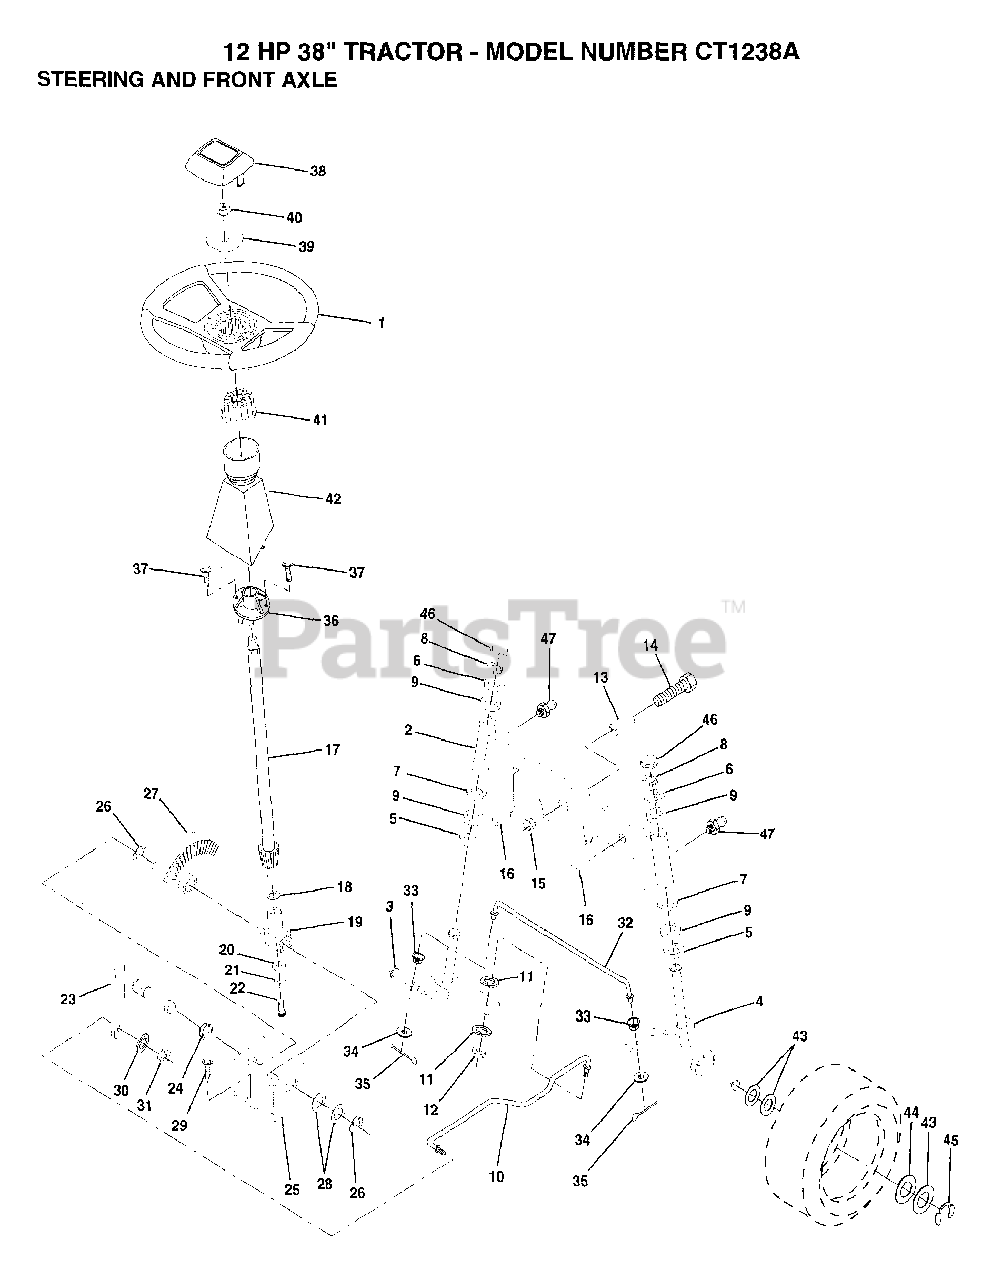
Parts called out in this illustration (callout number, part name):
3	SPINDLE LH
4	SPINDLE RH
5	WASHER .T
6	WASHER
7	WASHER
8	RING
9	COL. SRTG. BEAR.
11	LOCKWASHER
13	BEARING
14	BOLT HEX 5/8-11
15	"NUT-LOC,FLANGE LT"
16	AXLE PIN
17	SHAFT ASM
18	THRUST WASHER
19	SUPPORT.SHAFT
21	LOCKWASHER
22	"SCREW,SPECIAL"
24	NYLINER T
25	"BRKT,STEERING"
26	RING
27	GEAR SECTOR
28	RING
28	WASHER .T
29	SCREW
30	LOCKWASHER
32	TIE ROD
33	BUSHING.DRAGLINK
34	WASHER
35	COTTER PIN
38	ST WHL INSERT CAP
39	WASHER T
40	GRIPCO NUT
41	ADAPTER-WHEEL LT
42	"TUBE, STR SHAFT"
43	WASHER
44	WASHER
45	RING
46	CAP
47	ZERK M
